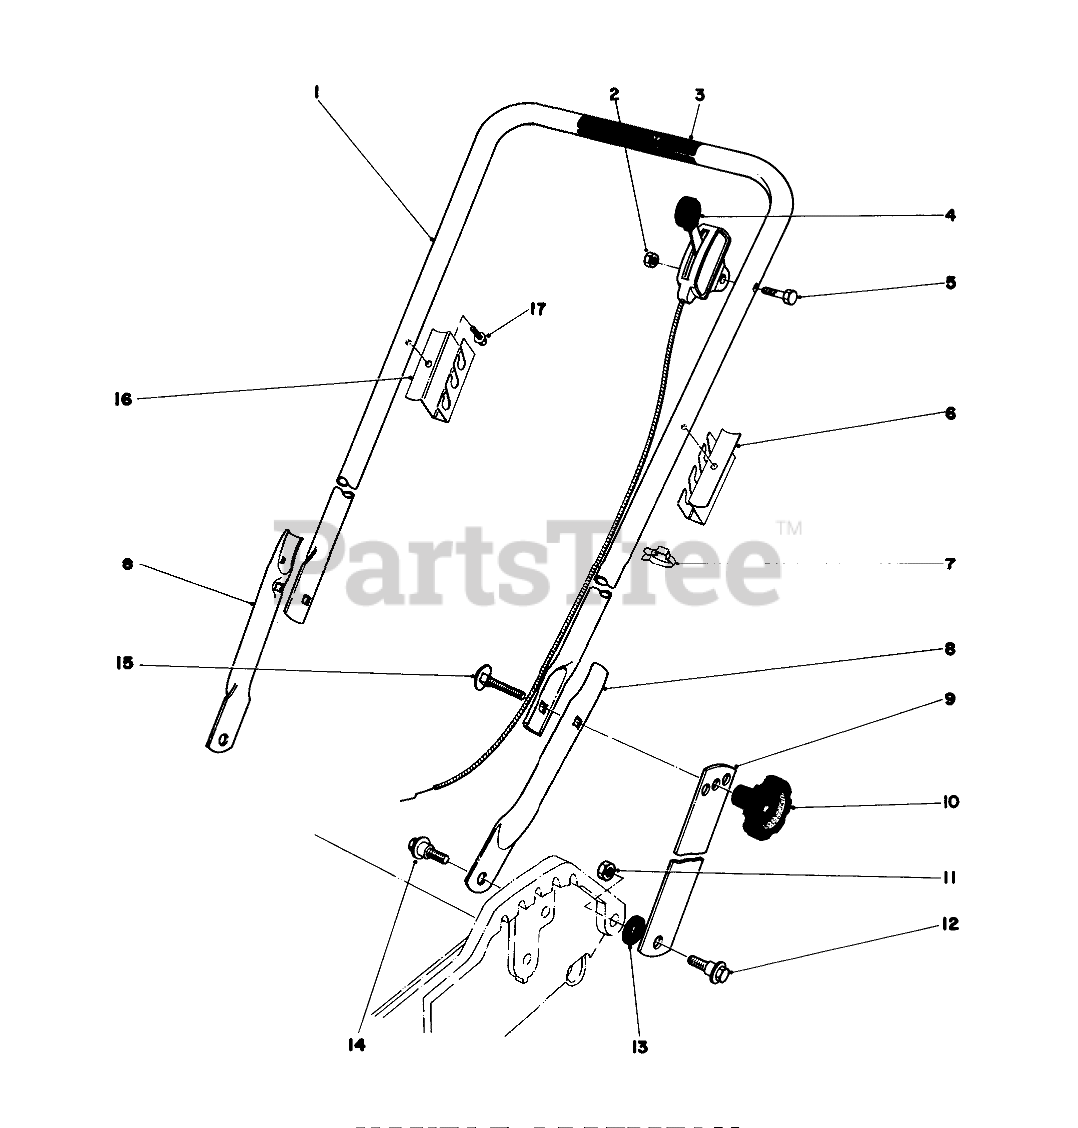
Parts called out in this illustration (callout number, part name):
1	Attachment Bag
2	GRASS BAG HANGER
3	Handle-Upper
4	Throttle Control
5	Traction Control
6	SCREW-HWHTF
7	Switch, Starter
8	Self Tapping Screw
9	Cover, Battery Pack
10	Lead Wire
11	Spacer-Battery
13	Container Battery Pack
14	Harness
15	Charger, Battery
16	Screw
17	CONTROL WIRE CLIP
18	Handle-Lower
19	Nut
20	Pin, Latch
21	Pin, Latch
23	Escutcheon Plate
24	Key
25	Battery Pack Assy. (Incl. Ref. 10-13)
26	Handle Pin
27	Nut
28	Terminal
29	PLUG TERMINAL
30	Decal
